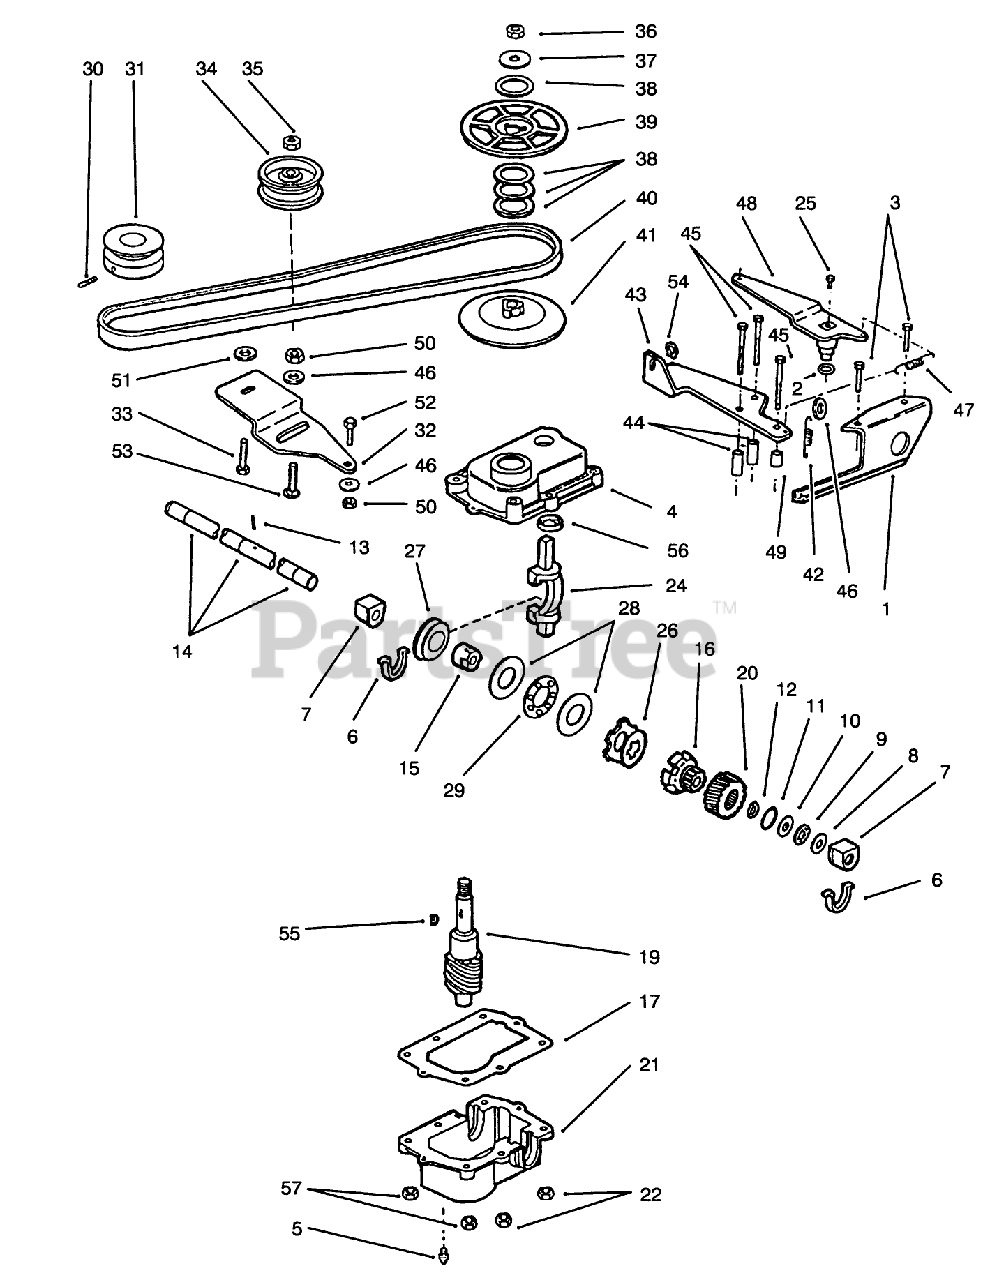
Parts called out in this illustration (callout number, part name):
4	UP/G-CSE&BRNG PL
7	BEARING & SEAL AY (12)
8	THRUST WASHER
10	WASHER-THRUST
12	RET RING
13	PIN DRIVE LOCK
16	DRIVER BROCKWAY
17	GASKET HOOSIER
20	WORM WHEEL
22	NUT-LOCK, NI
24	FORK SHIFT
25	SCREW SEMS SM
26	ORD KIT 684683
29	SVC LTR#28,ORD 684684
30	SET SCREW F
31	PULLEY ENG F
34	PULLEY IDLER NHI
35	NUT-JAM, LOCKING
36	NUT-LOCK, NI
39	PULLEY UPPER PL
40	V-BELT F
41	PULLEY LOWER PL
42	SPRING EXTEN D&B
43	CONDUIT ANCHOR BRKT
46	WASHER S
50	NUT-LOCK, NI
52	SCREW - HEX
54	RET. RING
55	KEY GALGER
56	GUIDE ELCO
57	NUT-LOCK, NI
